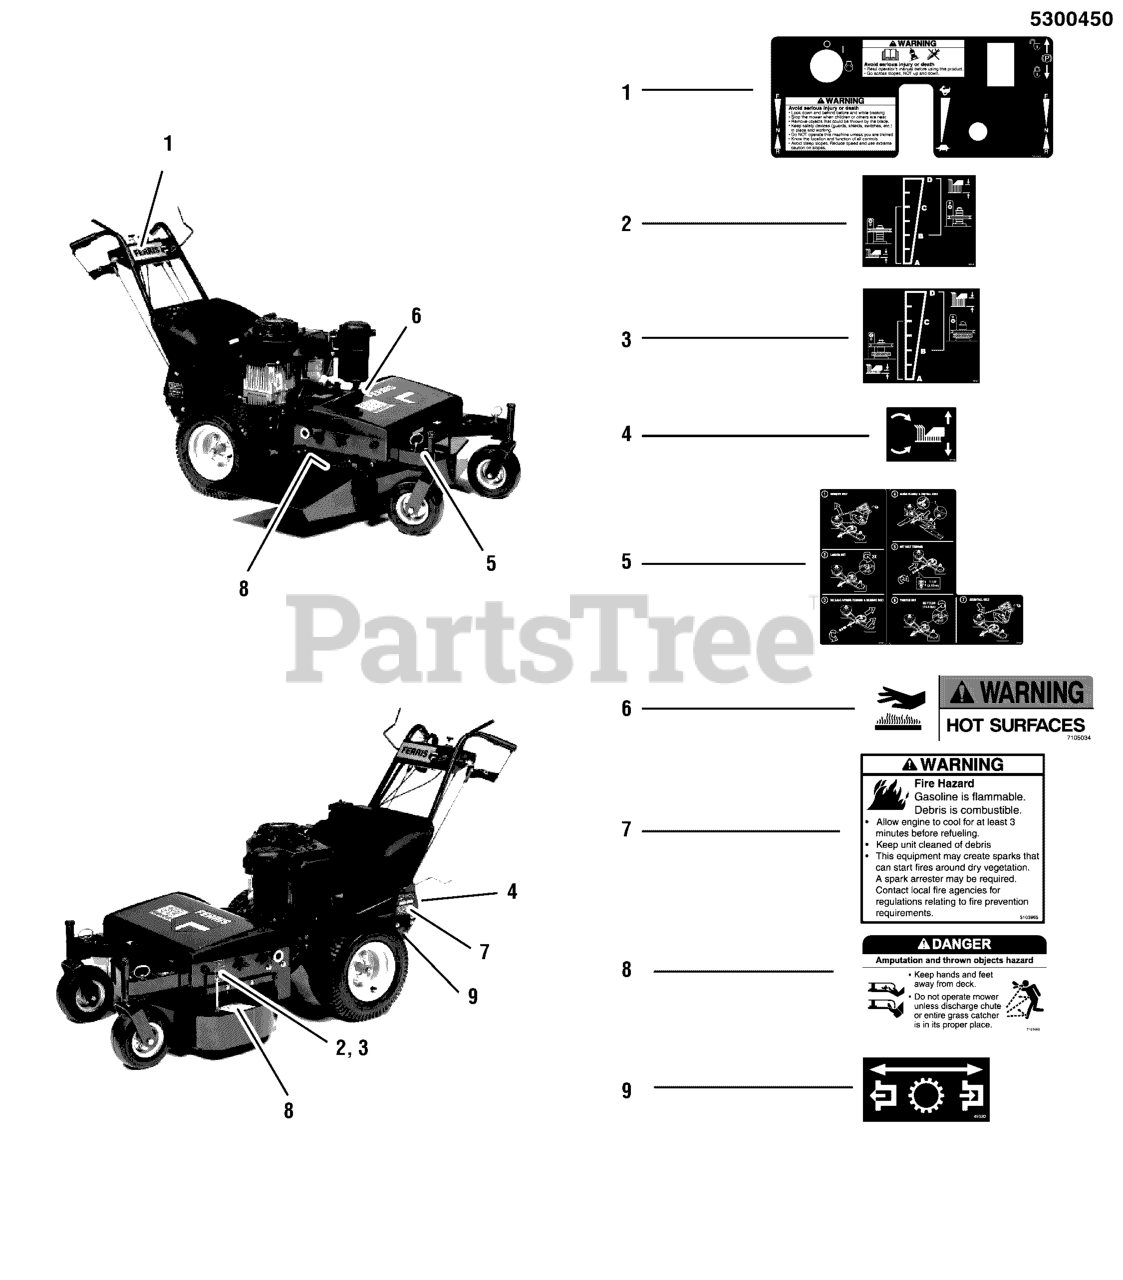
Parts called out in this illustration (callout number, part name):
1	DECAL, CONTROL PANEL, HC
2	DECAL, HEIGHT OF CUT
3	DECAL, HEIGHT OF CUT
4	DECAL, DECK HEIGHT ADJUST
5	DECAL, BELT R&R
6	DECAL, HOT SURFACE WARNING
7	DECAL, FIRE HARARD, 3.25W X 3.0H
8	DECAL, DANGER DO NOT OPERATE W/O DEFLECT
9	DECAL, HYDRO RELEASE
